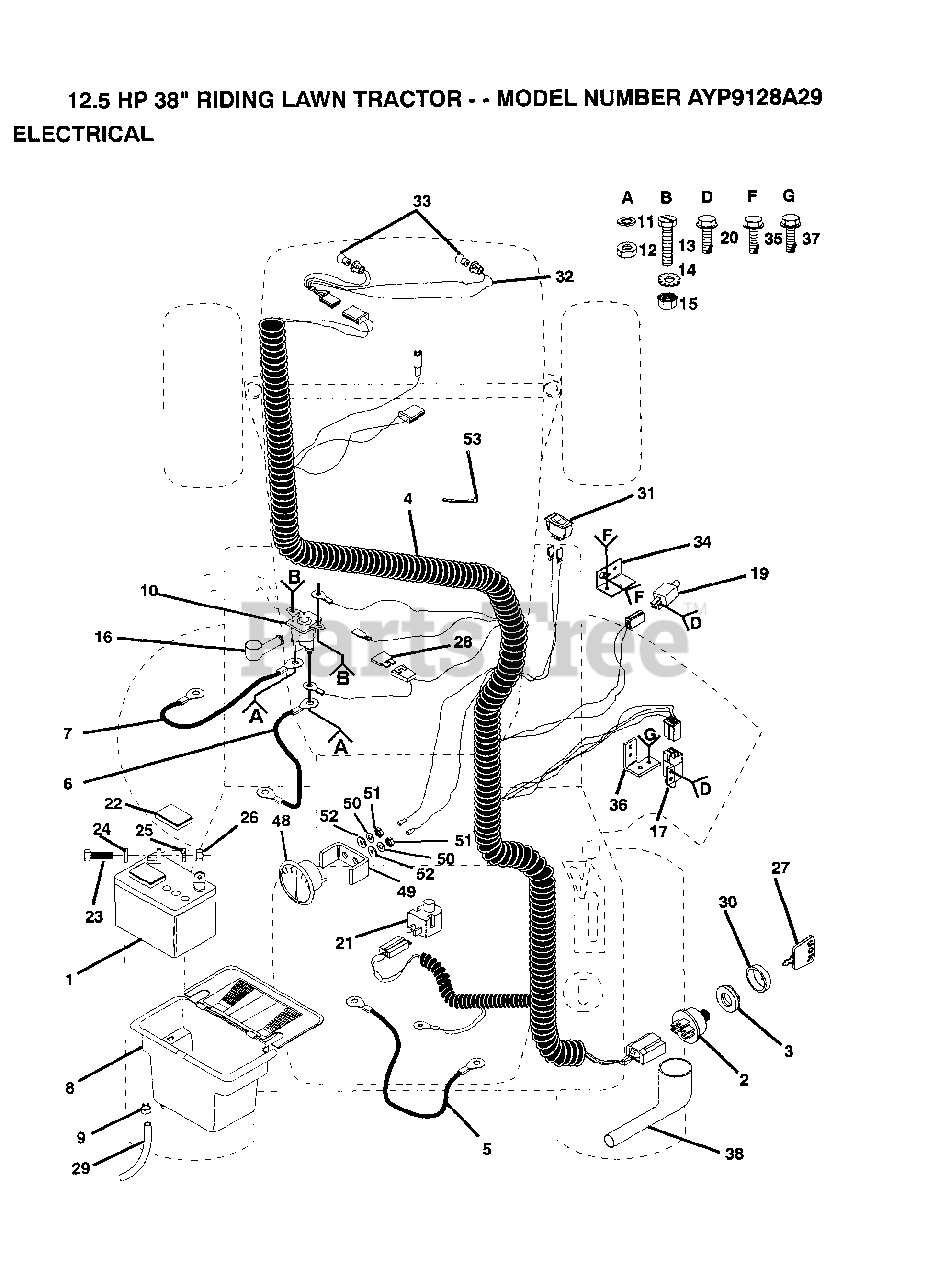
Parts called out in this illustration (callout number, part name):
3	NUT IGNITION
4	IGNITION HARNESS
5	CABLE T
7	"CABLE T, BATTERY"
8	BTRY CASE W/O LID
9	HOSE CLAMP T
12	NUT
13	BOLT
15	NUT
17	SWITCH INTERLOCKT
19	SWITCH-INTER. GT
20	SCREW
21	SWITCH SEAT
22	"CAP,BATTERY "
23	BOLT LT
24	WASHER
25	LOCKWASHER
27	KEY
28	FUSE HYT
31	SWITCH LT
34	SWITCH BRACKET
35	SCREW
36	BRACKET LT
37	SCREW
48	AMMETER T
52	WASHER
53	WIRE TIE
